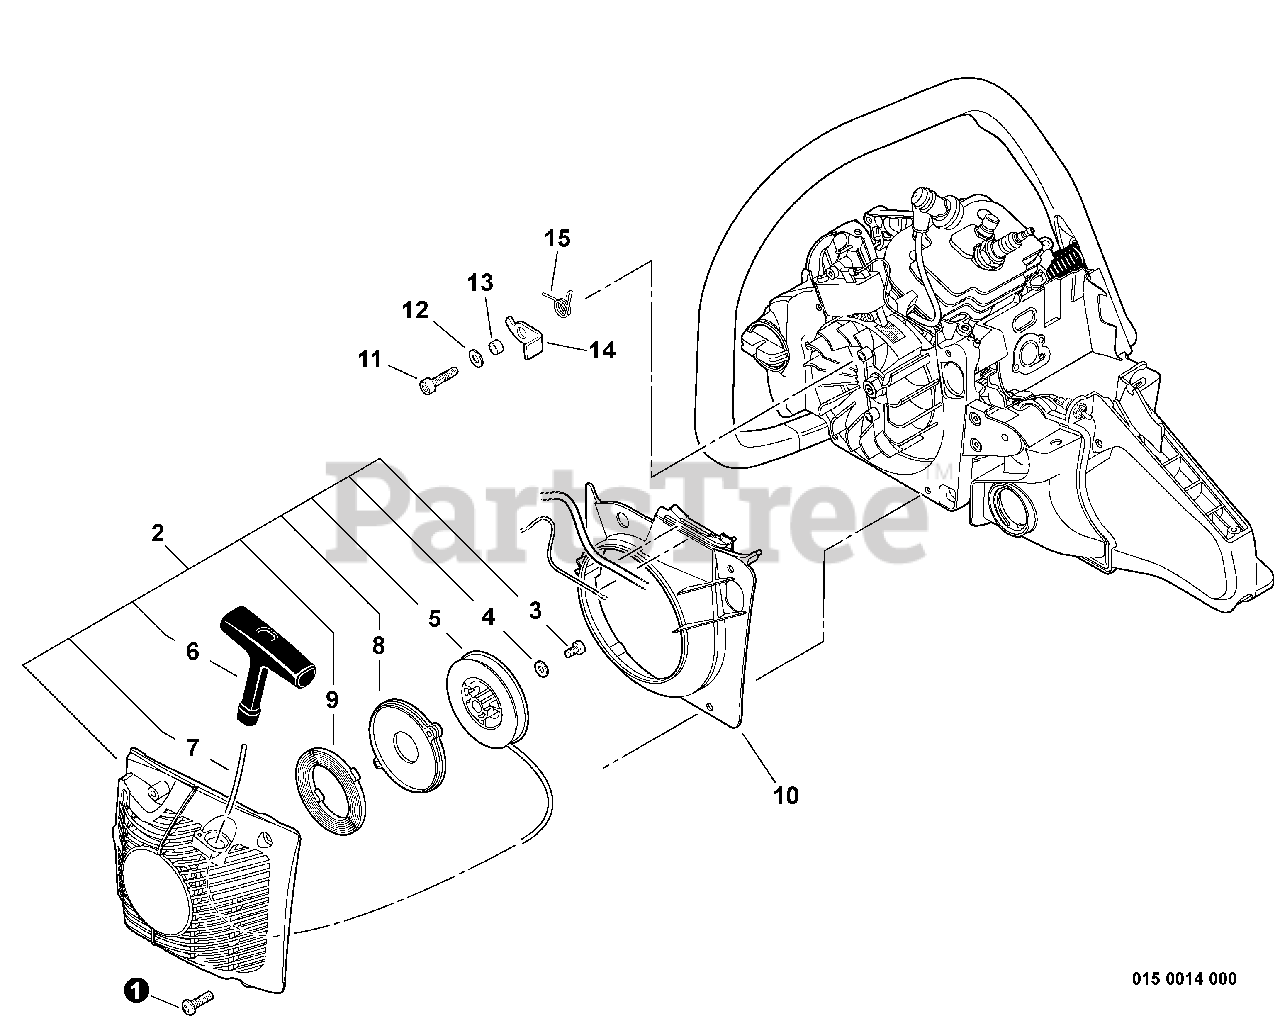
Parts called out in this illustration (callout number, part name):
1	SCREW - 5X20
2	STARTER ASSY
3	SCREW - 5X10
4	WASHER - 5
5	REEL, ROPE
6	GRIP, STARTER
7	ROPE, STARTER - 4X950
8	PLATE, STARTER
9	SPRING, REWIND
10	COVER, FAN
11	SCREW - 5X16
12	WASHER - 5
14	PAWL, STARTER
15	SPRING, RETURN
